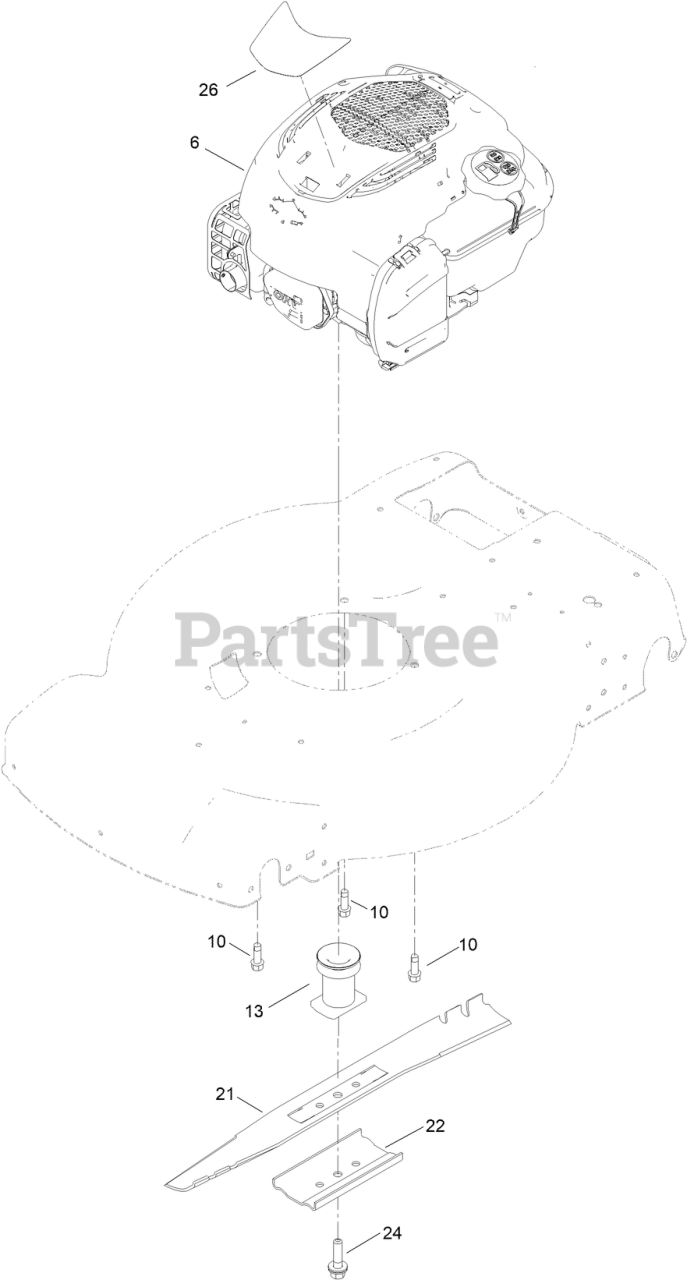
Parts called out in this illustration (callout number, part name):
6	ENGINE-BRIGGS 104M020043F1[675EXI ZS EU]
10	SCREW-THD FORM, HWH
13	DRIVER-BLADE
22	SUPPORT-BLADE
24	BOLT-BLADE
26	DECAL - BRIGGS 725 EX
